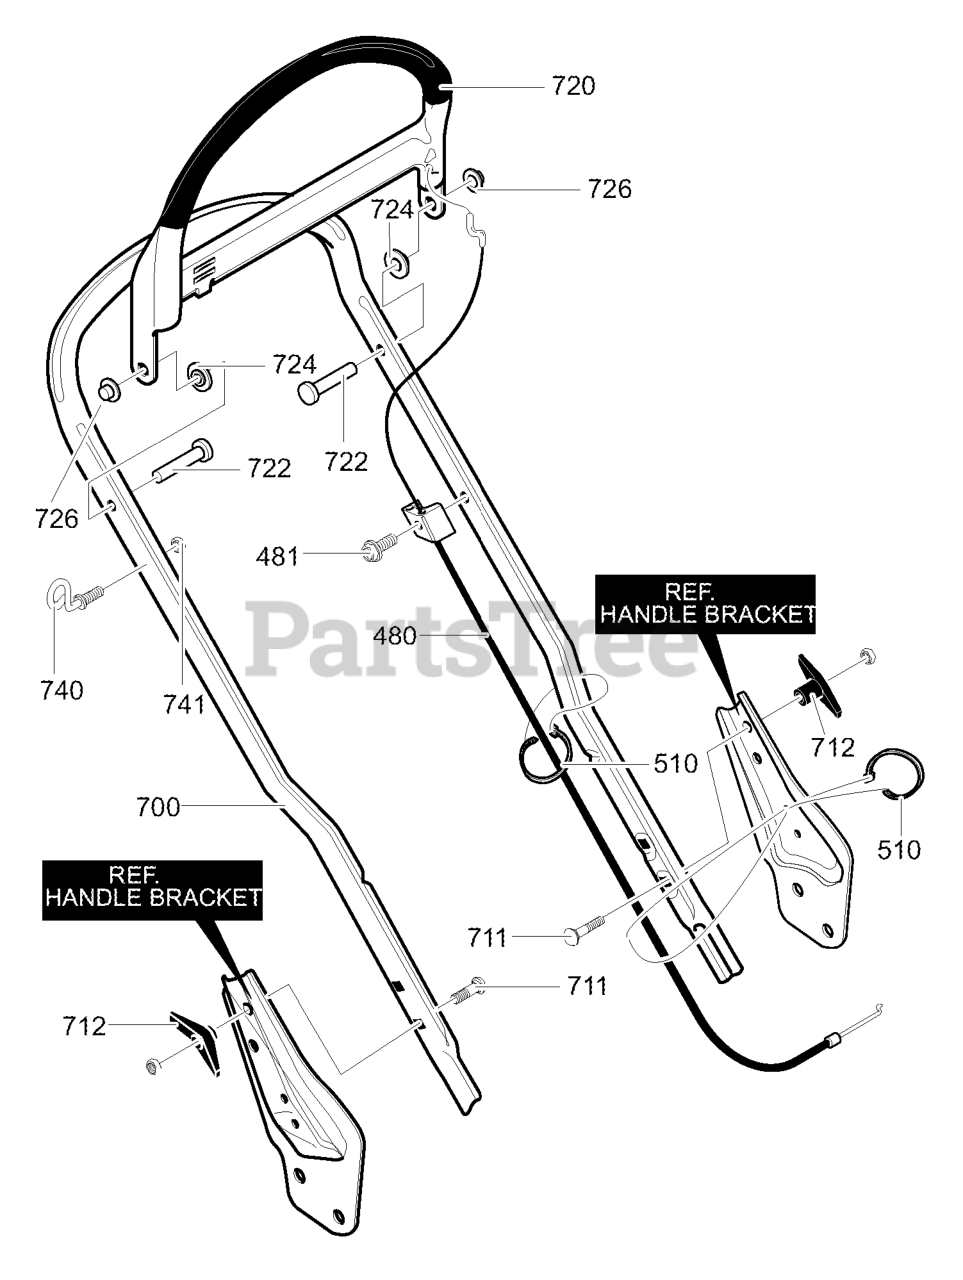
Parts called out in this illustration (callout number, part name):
480	CABLE, STOP
481	SCREW, 10-16X.75
510	CABLE TIE
711	CARR. BOLT, 5/16-18X2.00
712	WING KNOB
720	STOP LEVER
722	CLEVIS PIN
724	SPACER, FLANGE
726	CAP, RETAINER W/COVER
740	GUIDE, ROPE 1/4-20
741	NUT, 1/4-20
